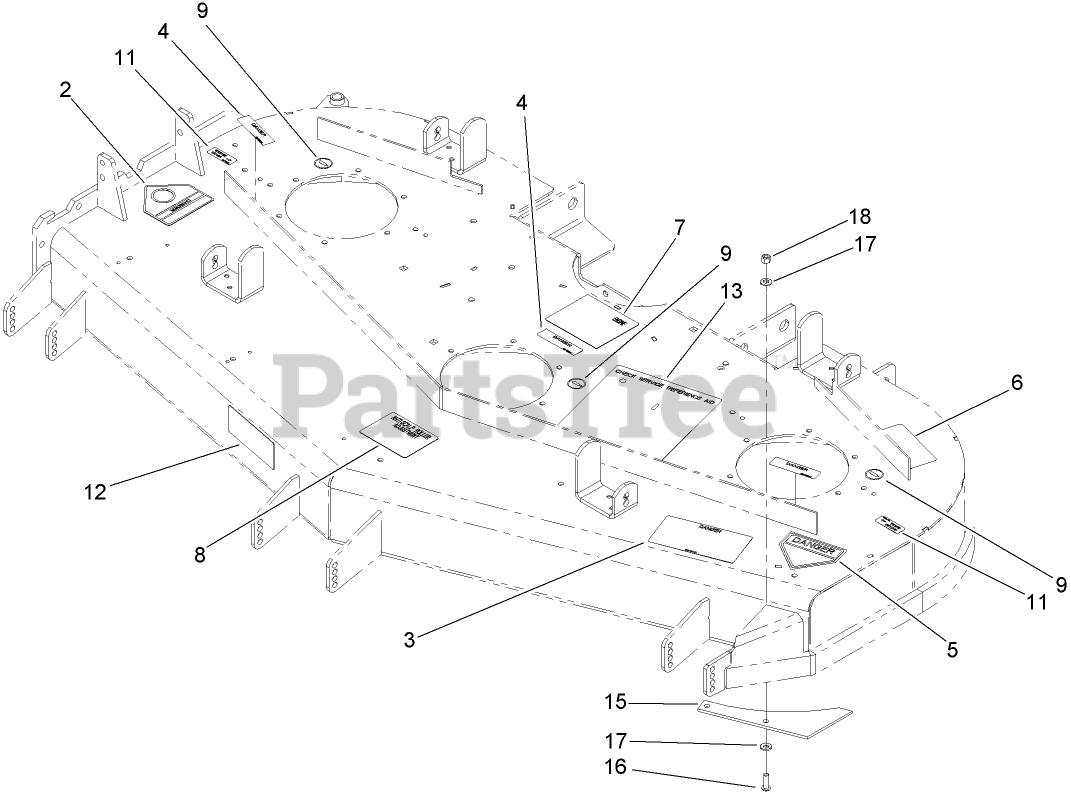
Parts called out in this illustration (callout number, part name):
2	DECAL-DANGER
3	DECAL-DANGER, THROWN OBJECT
4	DECAL-COVER, MISSING
5	DECAL-DANGER
6	DECAL-TORQUE
7	Decal-Routing, Belt
8	DECAL-SCALP, ANTI
9	DECAL-GREASE
11	Decal-Grease
13	Decal-Service, Check
15	PLATE-TURBO
16	SCREW-HSBH
17	WASHER-SPRING
18	NUT-LOCK, NI
